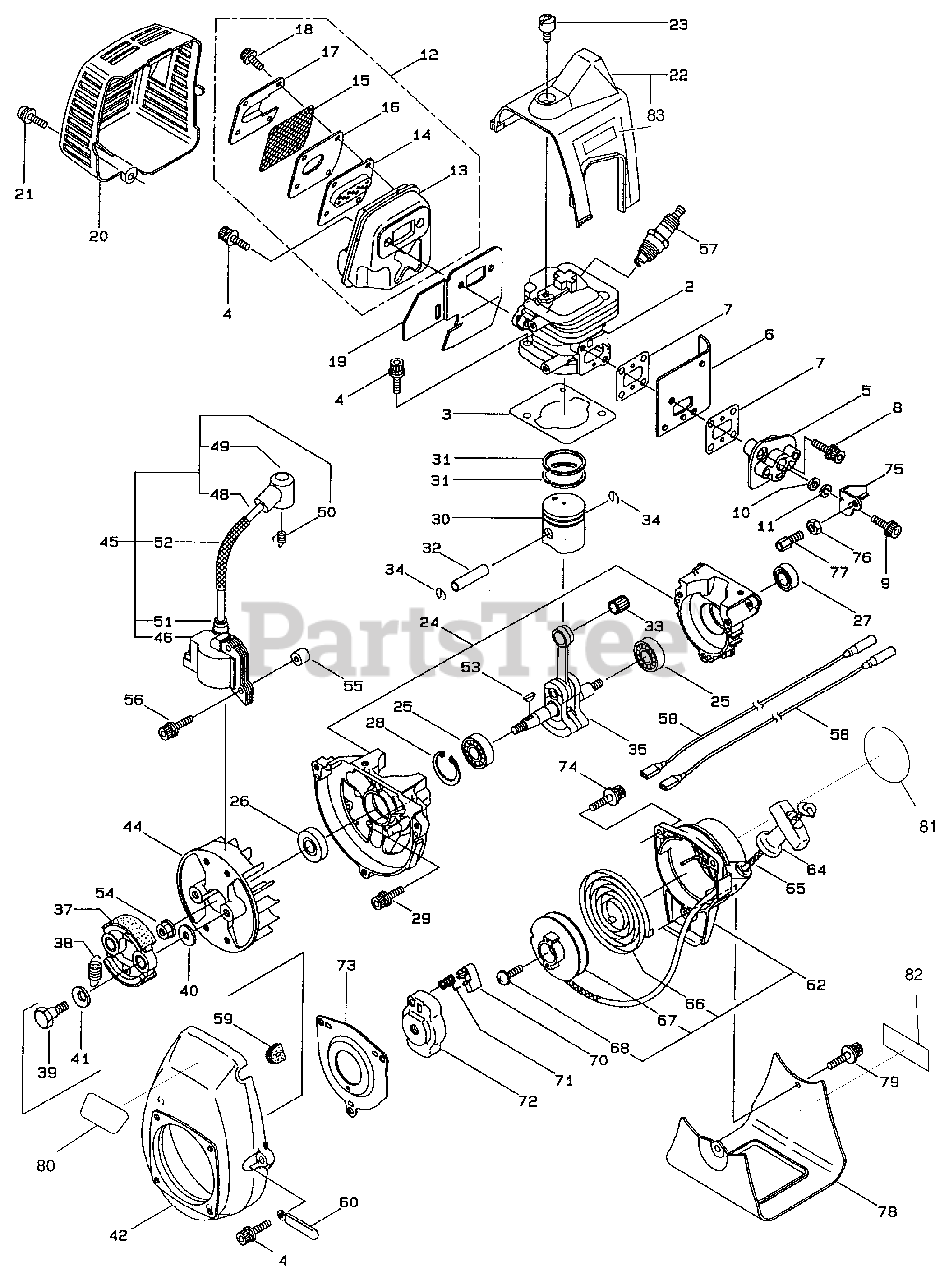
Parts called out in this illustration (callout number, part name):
2	Cylinder
4	Cap Screw
5	Insulator
6	Air Duct
8	Cap Screw
9	Cap Screw
11	Spring Washer
12	Muffler Assembly (Incl. Ref. #13-18)
13	Muffler Comp.
18	Cap Screw
20	Cover-Muffler
21	Cap Screw
22	Cylinder Cover
24	Crankcase
26	Oil Seal
27	Oil Seal
28	Snap Ring
29	Cap Screw
31	Piston Ring
32	Piston Pin
33	Bearing-Needle
34	Clip-Piston
35	Crankshaft-Connector Rod Assembly
37	Clutch Shoe
38	Spring-Clutch
41	Wave Washer
42	Fan Cover
44	Rotor-Fan
45	Ignition Coil Assembly (Incl. Ref. #46-52)
48	Spark Plug Wire
49	Plug Boot
50	Connector
52	Insulator
53	Woodruff Key
54	Nut-Rotor
56	Cap Screw
57	Spark Plug (NGK BPM6Y)
58	Wire-Coil Ground
62	Recoil Assembly (Incl. Ref. #63-68)
64	Starter Grip
65	Starter Rope
66	Spiral Spring
71	Return Spring
72	Pawl Case
74	Cap Screw
79	Cap Screw
80	Decal-Toro
81	Decal-Toro (Round)
82	Decal-Serial
83	Decal-Warning
